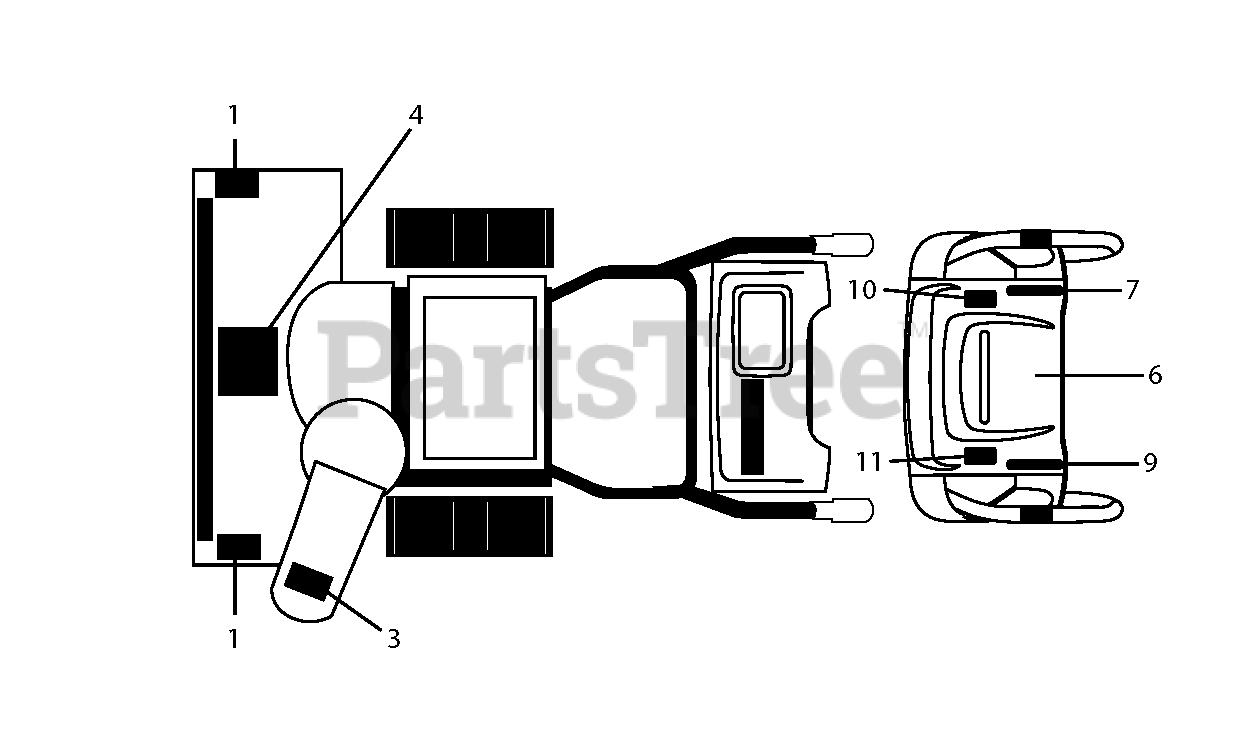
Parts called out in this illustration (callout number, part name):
1	DECAL.SNOWTHR.AUGER
3	DECAL.SNOWTHR.CHUTE.SAFETY
4	DECAL.SNOWTR.READ.OWN.MAN.E/F
6	DECAL.CONSOLE.SNOW.INST.ENG/FR
7	DECAL.CONS.RT.SPD/LEV/PWRST.
9	DECAL,LHTRIGGER
10	DECAL.CONSOLE.HAND.WARMER
11	DECAL,HEIGHTADJUST
